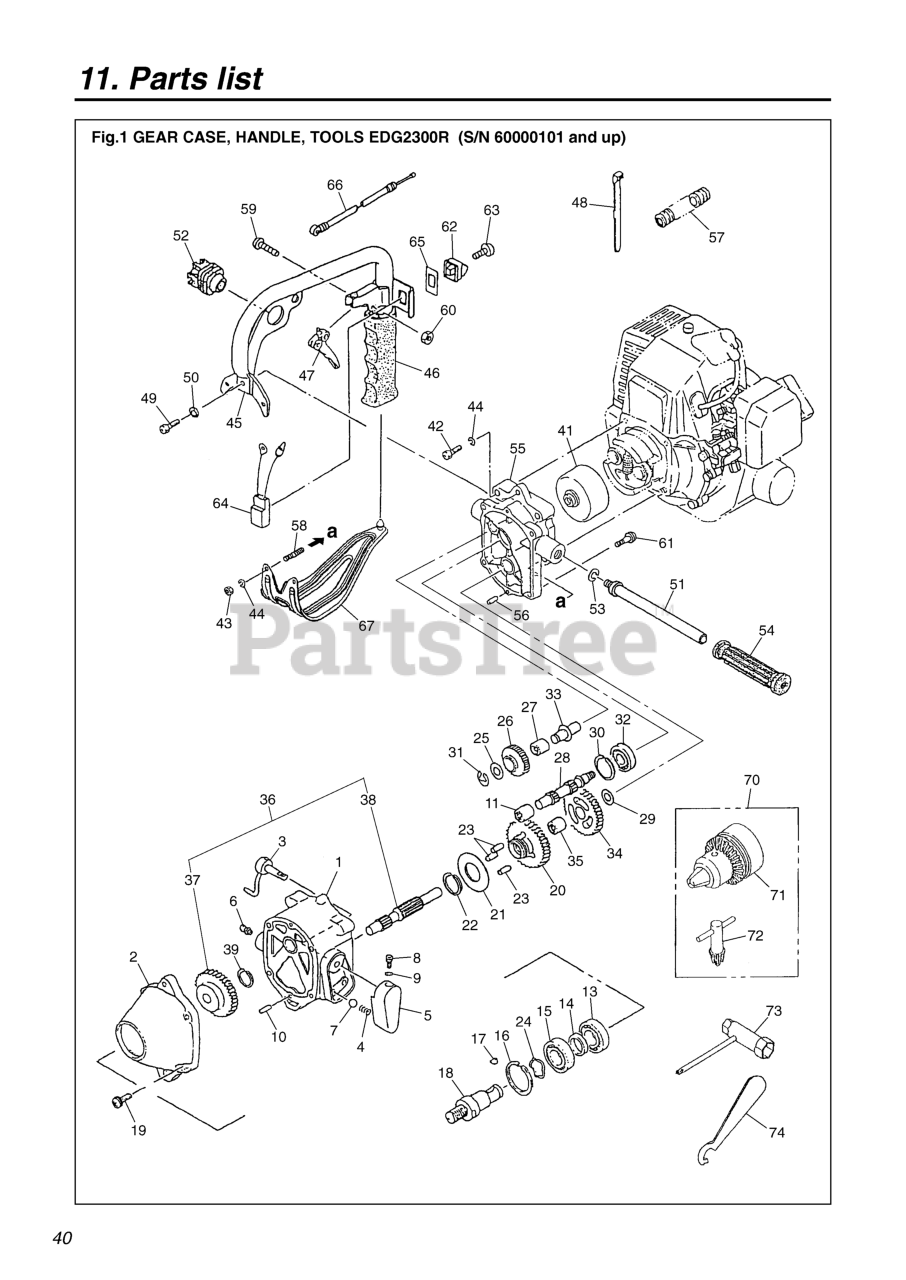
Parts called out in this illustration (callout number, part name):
1	GEARCASE A
2	GEAR CASE B COMP.
3	SHIFT FORK COMP.
4	SHIFT GUIDE SPRING
5	SHIFT LEVER
6	GREASE NIPPLE COMP.
7	STEEL BALL
8	HEX HOLE BOLT
11	NEEDLE BRG TLA912 1.5X5.8
13	BALL BEARING
14	BEARING WASHER
15	BALL BEARING
17	WOOD-RUFF KEY 3X13X5
18	DRIVE SHAFT
20	FORWARD GEAR
21	THRUST WASHER 2
23	NEEDLE ROLLER
24	WAVE WASHER
25	THRUST WASHER 0.8
27	NEEDLE BRG TLA912 1.5X5.8
28	INPUT SHAFT
29	THRUST WASHER 0.8
31	E TYPE STOP RING
32	BALL BEARING
33	IDLE SHAFT
34	REVERSE GEAR
35	NEEDLE BRG TLA912 1.5X5.8
36	GEAR SET
37	GEAR 4
38	COUNTER SHAFT
41	CLUTCH HOUSING COMP.
43	NUT
44	WASHER
45	HANDLE COMP. A
46	HANDLE GRIP A
47	THROTTLE LEVER
48	CORD CLAMP
49	PLUS BOLT
50	WASHER
51	HANDLE COMP. B
52	CHUCK HANDLE HOLDER
53	WASHER
54	HANDLE GRIP
55	CLUTCH CASE COMP.
57	CORRUGATED TUBE 7X290L
58	STUD BOLT 6X26
59	SCREW
60	HEX NUT
62	BUTTON STOP
63	SCREW
64	STOP SWITCH COMP.
65	STOP BUTTON MARK
66	THROTTLE WIRE 370+50
67	HANDLE SUPPORT COMP.
70	CHUCK HANDLE SET
71	DRILL CHUCK ASS
72	CHUCK HANDLE COMP.
73	COMBI BOX SPANNER 13X19
74	SPECIAL WRENCH 31
